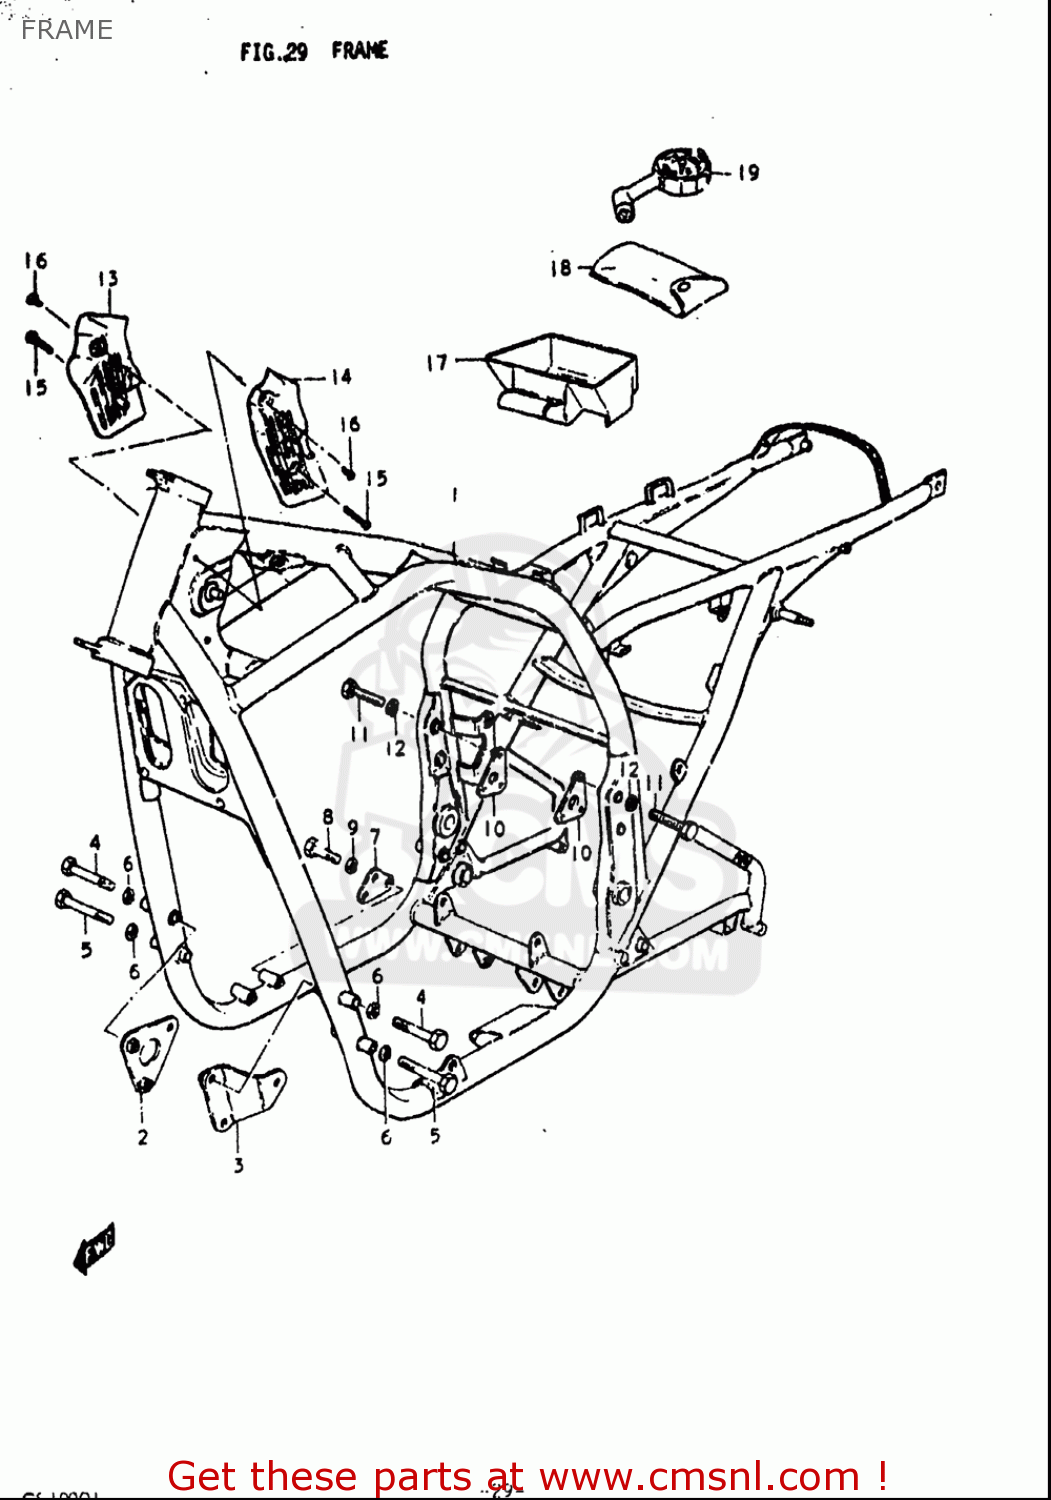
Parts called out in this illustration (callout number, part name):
4	BOLT
5	BOLT
6	WASHER,LOCK
7	PLATE,ENG MTG NO.2
8	BOLT
9	WASHER,LOCK
10	PLATE,ENG MTG NO.4
11	BOLT
12	WASHER,LOCK
15	SCREW
16	SCREW
18	TOOL ASSY
